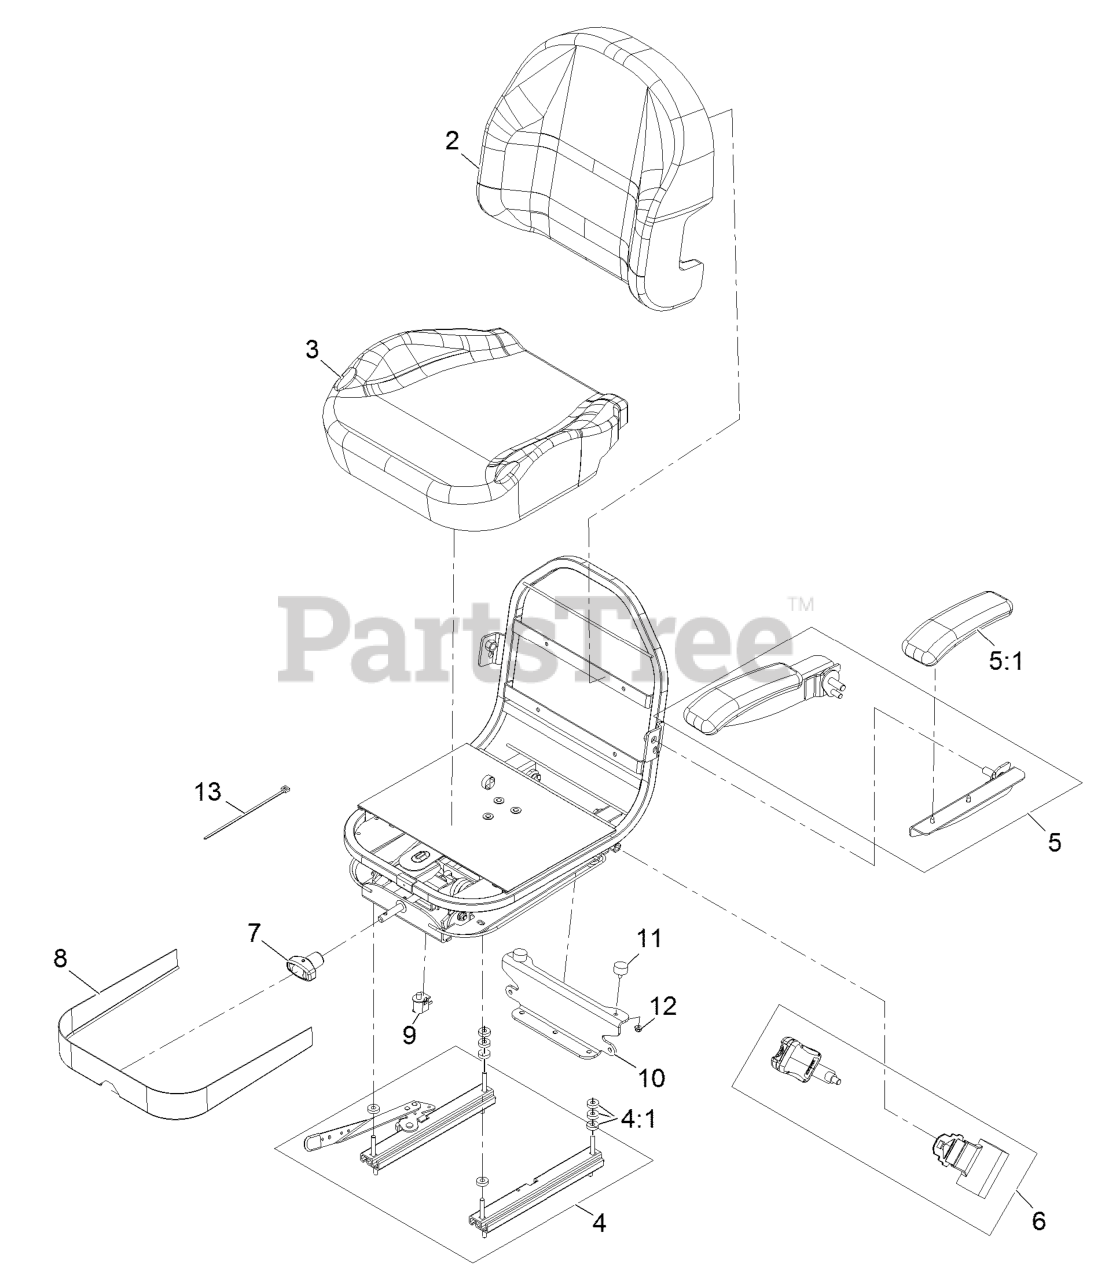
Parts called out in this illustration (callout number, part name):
2	COVER-SEAT BACK
3	COVER-CUSHION
4	KIT-TRACK-SEAT 4"
5	ARMREST KIT
5:1	CUSHION-REST, ARM
7	KNOB-ADJUSTER
8	COVER-SKIRT W/FASTENERS
9	SWITCH-BAIL
10	PLATE-SEAT SUPPORT
11	BUMPER-RUBBER
13	TIE-PLASTIC
